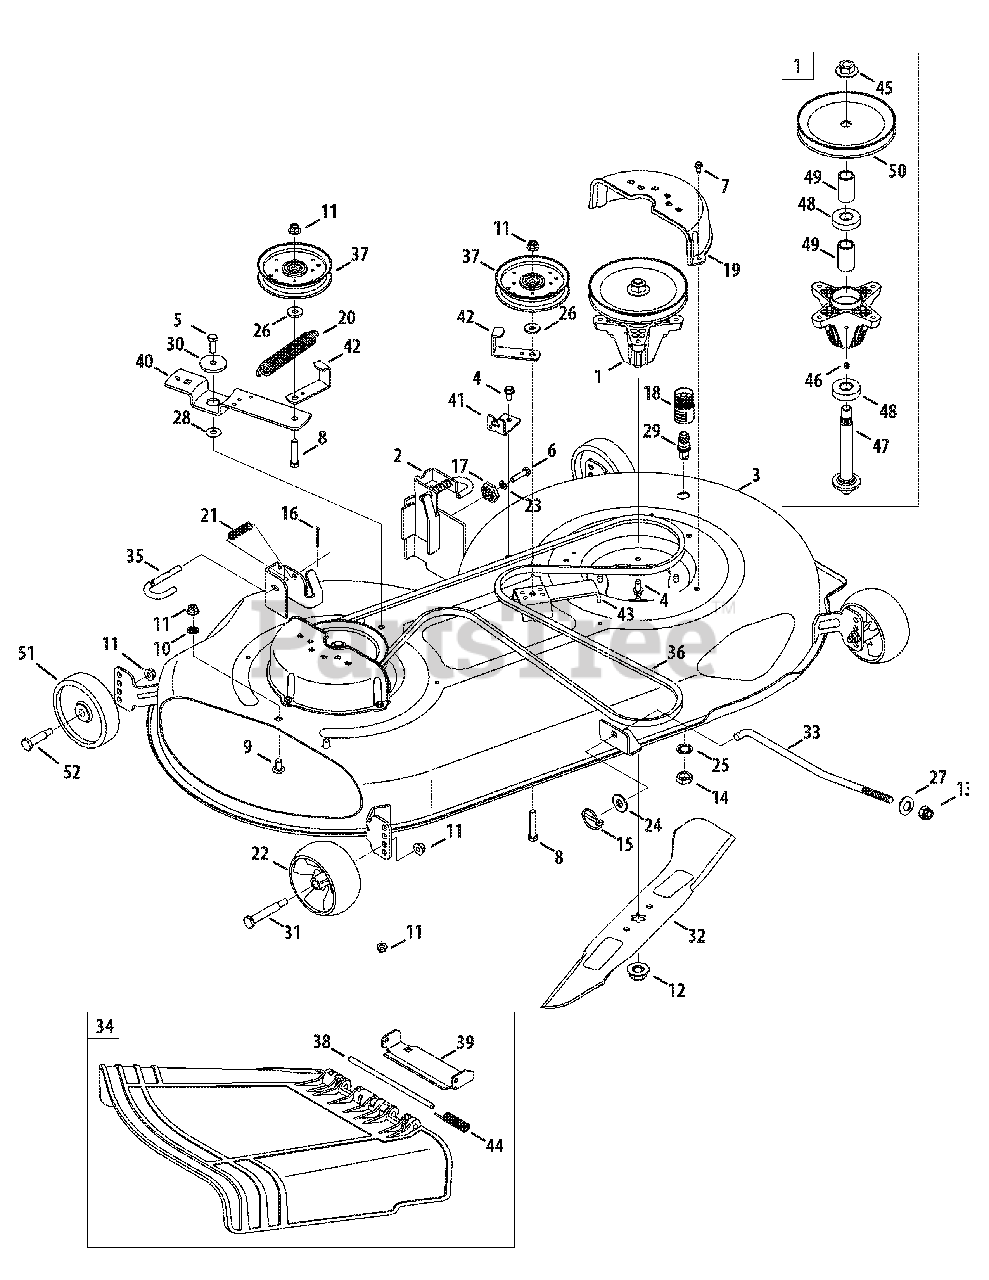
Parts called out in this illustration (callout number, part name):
1	Spindle Assembly, Pulley 6.93 Dia.
2	Bracket Assembly, Deck, Hanger LH
3	Deck Assembly, Offset, 46"
4	Screw, Self-tapping, 5/16-18, .750,
5	Hex Screw, 3/8-16, 1.00, Gr5, Std
6	Hex Screw, 5/16-18, 1.25, Gr5, Std
7	Screw, Self-tapping, 1/4-20, 0.500,
8	Hex Screw, 3/8-16, 2.00, Gr5, Std
9	Bolt, Carriage, 3/8-16, 0.75, Gr1
10	Nut, Push, 3/8
11	Nut, Flange Lock, 3/8-16, Nylon
12	Nut, Flange, 5/8-18
13	Nut, 1/2-13
14	Nut, Hex, M16-1.5 Din 936
15	Pin, Lynch, .1875
16	Pin, Cotter, 1/8 X 1.25
17	Gear, Deck, Adj
18	Adapter, Water
19	Cover, Belt, Universal
20	Spring, Extension, .94 Dia. X 6.74
21	Spring, Compression, .535 OD X 1.75
22	Wheel, Deck, 5.0 Dia. Ball
23	Washer, Lock, 5/16, Regular Duty
24	Washer, Flat, .531 X 1.25 X .100
25	Washer, Lock, 5/8, Int. Tooth
26	Washer, Flat, .385 X .870 X .092
27	Washer, Bell, .63 X 1.25 X .18
28	Washer, Flat, .385 X 1.0 X .030
29	Port, Water
30	Spacer, Shoulder, .8840 X .190
31	Bolt, Shoulder, .496 X 2.50, 3/8-16
32	Blade, Cut, 23.25" 2-In-1, Cub
33	Rod, Lift, Deck, Front, 13.7
34	Chute Assembly, 46" Deck
35	Rod, Deck Release .375 Dia.
36	Belt, V-Type, A Sec
37	Pulley, Idler, 4.25" Dia.
38	Pin, Hinge, 7.96
39	Bracket, Chute
40	Bracket, Idler, Pivot
41	Bracket, Cable, Deck Engage
42	Bracket, Guard, Belt, 4.25 Pulley
43	Bracket, Support, Stationary Idler
44	Spring, Torsion, .44 I.D. X 2.0
45	Nut, Flange, 5/8-18
46	Lube Fitting, 3/16
47	Shaft, Spindle, 6.11
48	Bearing, Ball, .787 X 1.85 x.551
49	Spacer, .792 X 1.060 X 1.860
50	Pulley, Deck, 6.93 Dia.
51	Wheel, Deck 5.0 x 1.38
52	Bolt, Shoulder, .496 x 1.525, 3/8-16
